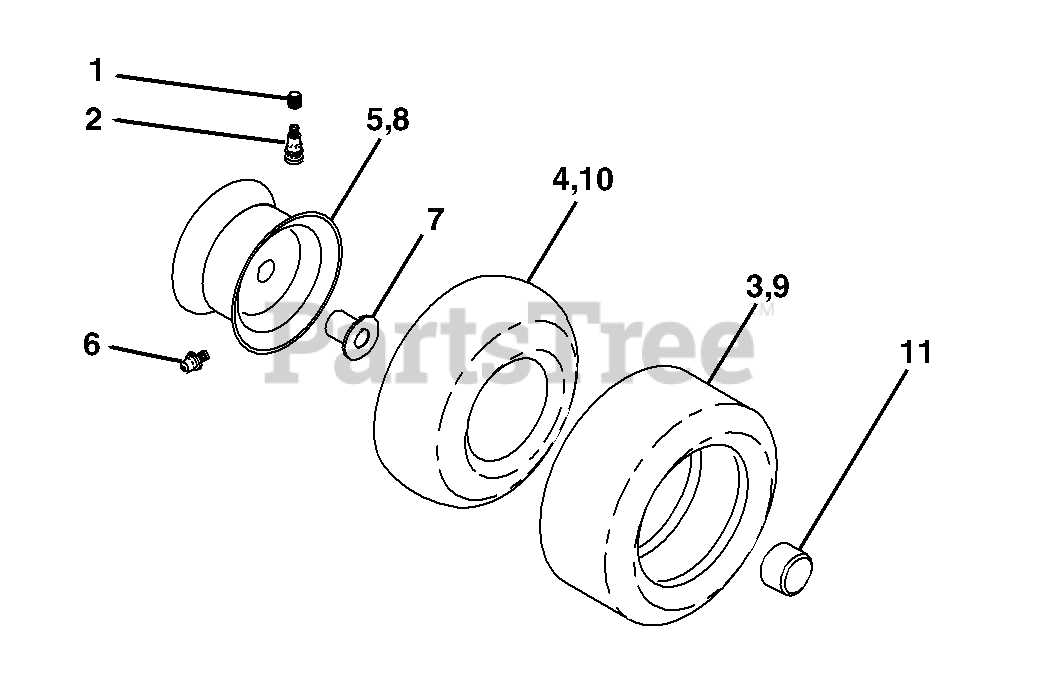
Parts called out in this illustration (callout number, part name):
1	Cap Valve Tire
2	Stem Valve
3	Tire F Ts 15 X 6 0 - 6 Service
4	Tube Front (Service Item Only)
5	Rim Asm 6"front White Service
6	Fitting Grease (Front Wheel Only)
7	Bearing Flange (Front Wheel Only)
8	Rim Asm 8"rear White Service
9	Tire R Ts 18x9.5-8 C Service
10	Tube Rear (Service Item Only)
11	Cap Axle Blk 1 50 X 1 00
